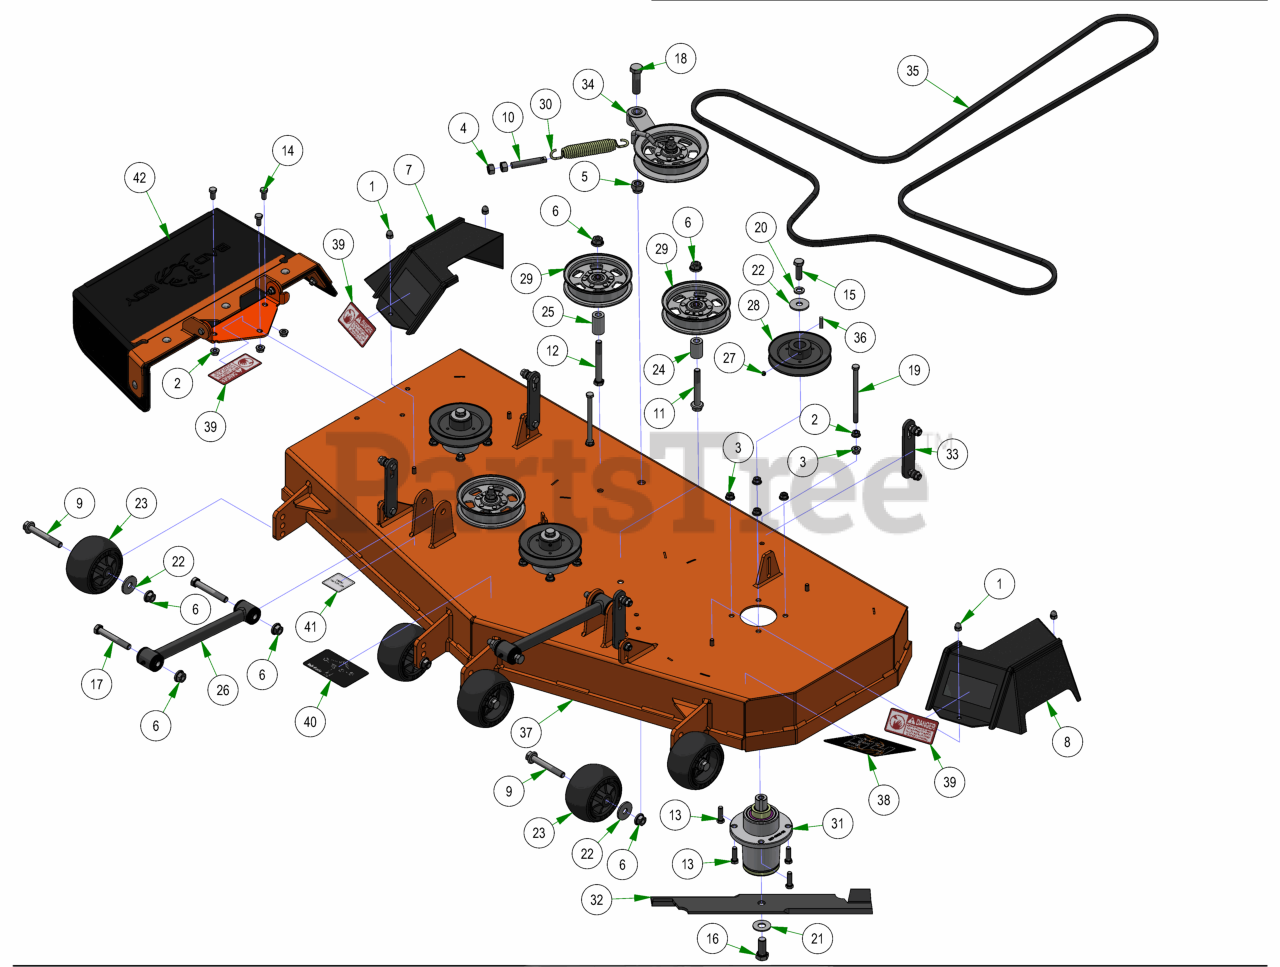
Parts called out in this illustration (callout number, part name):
1	5/16-18 ACORN NUT HIGH-CROWN ZC
2	3/8-16 HEX SERRATED FLANGE NUT HARD/ZINC
3	3/8-16 NYLON INSERT FLANGE LOCKNUT (GR.F) ZINC
4	1/2-13 HEX NUT ZINC
5	5/8-11 NYLON INSERT LOCKNUT ZINC
6	1/2-13 NYLON INSERT FLANGE LOCKNUT ZINC
7	2021 Maverick 54”/60” RH Pulley Cover
8	2021 Maverick 54”/60” LH Pulley Cover
9	1/2-13 X 90MM HEX FLANGE BOLT W/SHOULDER (GR.8) ZINC
10	All Thread
11	1/2-13 X 3-1/2 HEX FLANGE BOLT (GR.8) ZINC
12	1/2-13 X 4 HEX CAP SCREW (GR.8) ZINC YELLOW
13	3/8-16 X 1-1/4 HEX CAP SCREW (GR.5) ZINC
14	3/8-16 X 3/4 HEX CAP SCREW (GR.5) ZINC
15	1/2-20 X 1-1/2 HEX CAP SCREW (GR.5) ZINC
16	5/8-18 X 1-1/2 HEX CAP SCREW (GR.8) ZINC YELLOW
17	1/2-13 X 3-1/2 HEX CAP SCREW (GR.5) ZINC
18	5/8-11 X 2-1/4 HEX CAP SCREW (GR.5) ZINC
19	3/8-16 X 5-1/2 HEX CAP SCREW (GR.5) ZINC
20	1/2 SPLIT LOCKWASHER (GR.8) ZINC/YELLOW
21	5/8 USS FLAT WASHER (1-3/4" OD) GR.8 ZINC YELLOW
22	1/2 BELLEVILLE WASHER (1-5/8 OD X .140 THK) ZINC
23	Deck Wheel
24	.502 ID X .750 OD X 1.500 Long Spacer
25	1 3/4" Pulley Spacer
26	Hybrid Turnbuckle/Deck Locator
27	5/16-24 X 1/4 SOCKET SET SCREW (CUP PT) PLAIN
28	5.25" Deck Spindle Pulley
29	5-3/4 Idler Pulley
30	Deck Idler Spring
31	Spindle Assembly
32	54" Fusion Blade for Avenger/ZT/Mav/Outlaw/Revolt
33	Deck Hanger Assembly
34	Maverick HD & Down Deck Idler Assembly
35	B155.75 Deck Belt
36	1/4 X 1 SQ MACHINERY KEY 1018 STL PLN
37	2025 54" x 5" Deck
38	54" Grip Deck Decal
39	Danger Decal-Spindle/Discharge
40	Deck Belt Route Decal
41	Deck Impact Patent Decal 9591803
42	Discharge Chute Assembly
